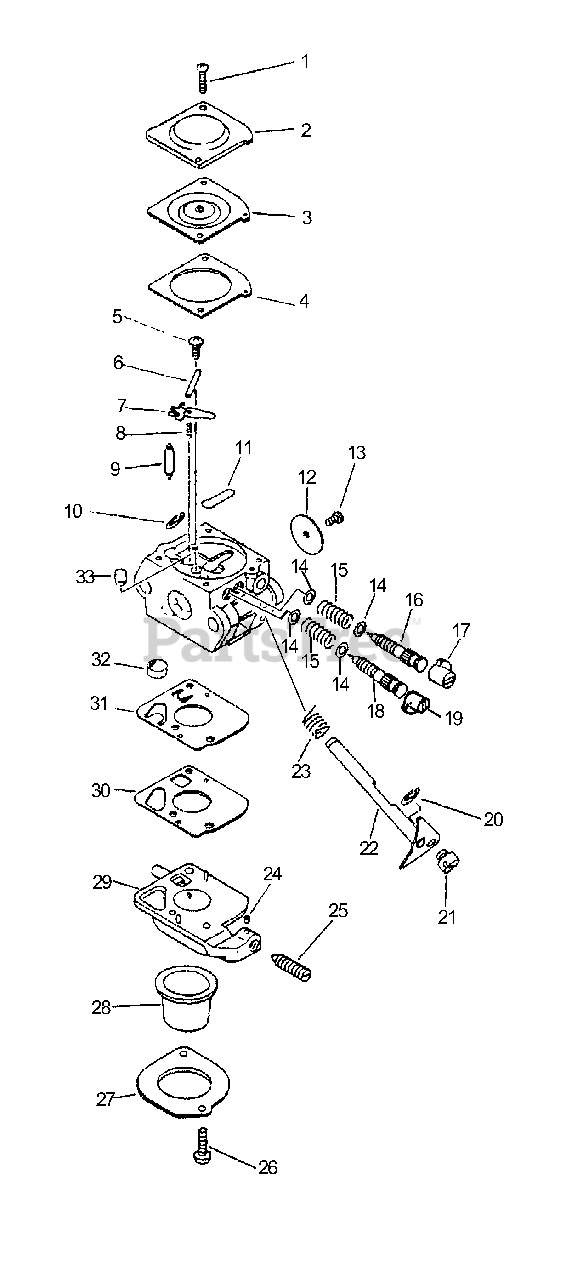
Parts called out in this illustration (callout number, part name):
2	COVER, METERING DIAPHRAGM
3	DIAPHRAGM, METERING
4	GASKET, METERING
6	PIN, METERING LEVER
7	LEVER, METERING
8	SPRING, METERING LEVER
9	VALVE, NEEDLE
11	PLUG, WELCH
12	VALVE, THROTTLE
15	SPRING, NEEDLE
16	NEEDLE, MIXTURE
17	CAP, LIMITER - WHITE
18	NEEDLE, HIGH SPEED
19	CAP, LIMITER - RED
22	SHAFT, THROTTLE
23	SPRING, THROTTLE RETURN
24	PIECE, FRICTION
25	SCREW, IDLE ADJUST
27	RETAINER
28	BULB, PURGE
29	BODY ASSY, PURGE
30	GASKET, PUMP
31	DIAPHRAGM, PUMP
32	STRAINER
33	NOZZLE, CHECK VALVE
